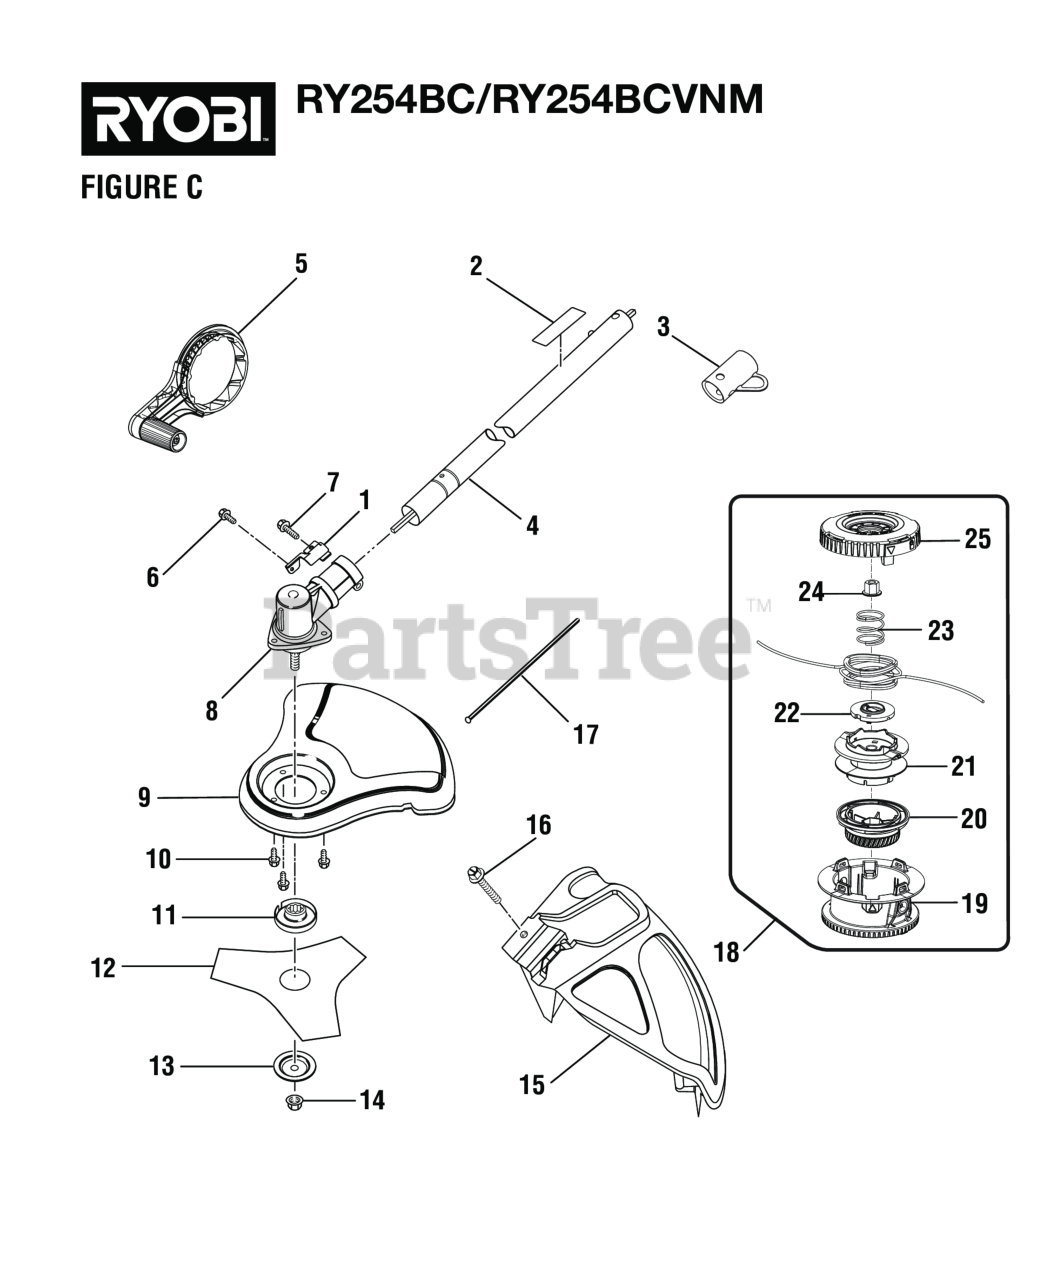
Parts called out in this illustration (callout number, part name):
1	Grass Deflector Clamp
2	Brushcutter Safety Label
3	Storage Hanger Cap
4	Lower Straight Shaft Boom Assembly (Inc. Key Nos. 1-2)
5	Crank Handle
6	Screw (1/4-20 x 1-1/4 in., Hex Washer Hd. S.T.)
7	Screw w/Washer (10-24 x 5/8 in., Hex Hd. T.F.)
8	Gear Case Assembly
9	8 in. Blade Guard
10	Screw w/Washer (10-24 x 1/2 in., Slotted Hex Hd.)
11	FLANGED WASHER
12	BLADE (TRI-ARC(TM))
13	CUPPED WASHER
14	Lock Nut (M8 x 1.25 in., Left Hand Threads)
15	Grass Deflector Assembly
16	SCREW (#1/4-20 X 1-1/4 in. HEX WASHER HD.)
17	Gear Head Locking Tool
18	Trimmer Head Assembly (.095) (Inc. Key Nos. 19-25)
19	Bump Head
20	Bump Knob (Green)
21	Spool Assembly
22	String Guide
23	Compression Spring
24	Hex Nut (M8, Left Hand Threads)
25	Locking Assembly
